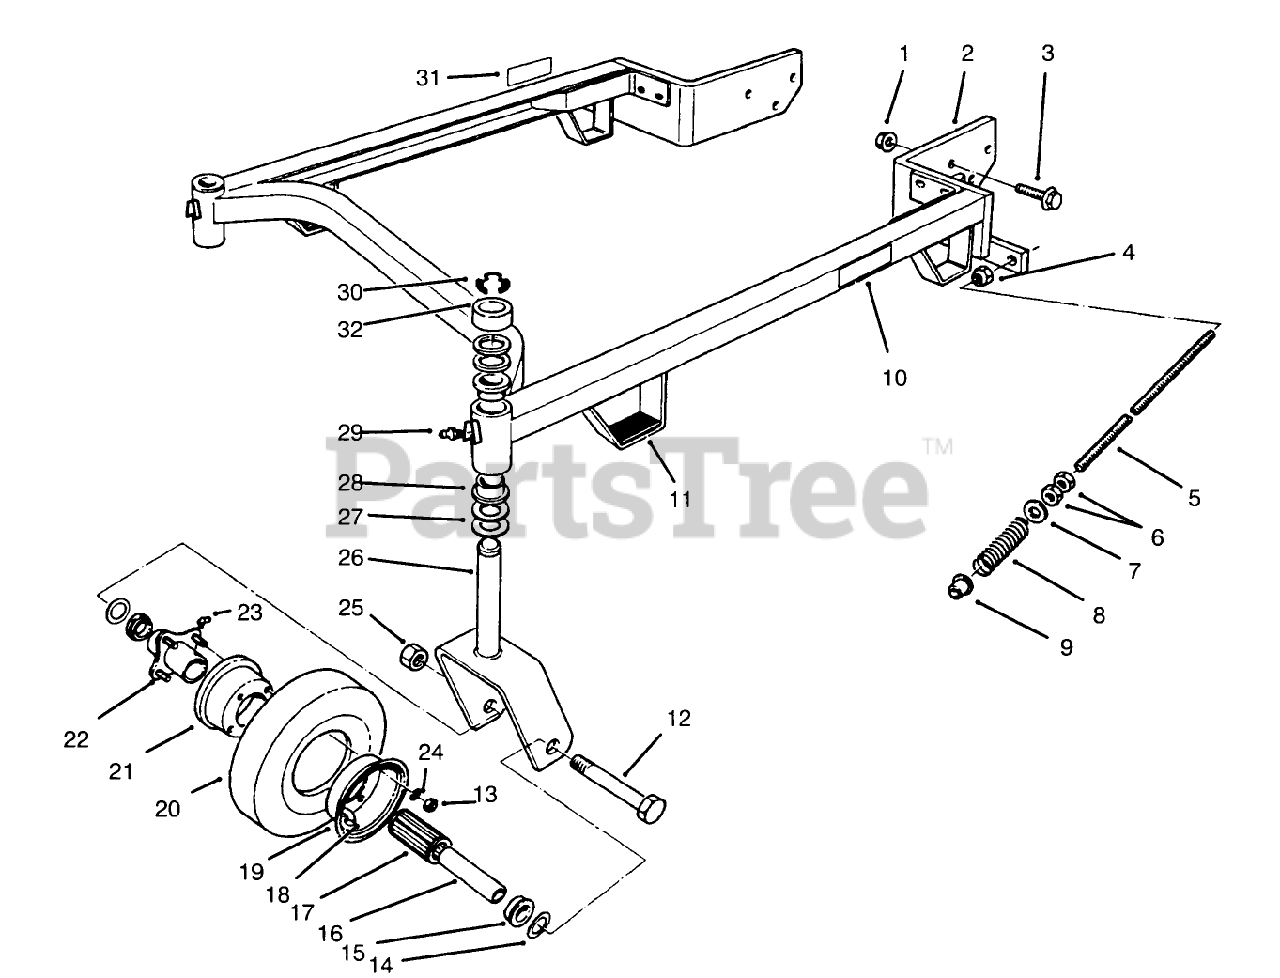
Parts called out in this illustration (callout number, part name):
1	NUT-HF
2	Frame-Suspension (Incl. Ref. #28)
3	SCREW-HHF
4	NUT-LOCK, NI
5	SHAFT-ADJUSTING
6	NUT-JAM
7	WASHER
8	SPRING
9	BUSHING-FLANGE
10	DECAL-HOC, LH
11	CUSHION-RUBBER
12	SCREW-HH
13	NUT-HEX
14	WASHER-FLAT
15	BEARING-OUTSIDE
16	SPANNER-TIRE
17	BEARING-ROLLER
18	TUBE-INNER (W/VALVE)
19	FEMALE WHEEL HALF
21	MALE WHEEL HALF
22	HUB-CENTER
23	FITTING-GREASE
24	WASHER-FLAT
25	NUT-HEX
26	Fork
27	WASHER-THRUST
28	BUSHING
29	FITTING-GREASE
30	RING-RETAINING
31	DECAL-HOC, RH
32	SPACER-CASTOR
